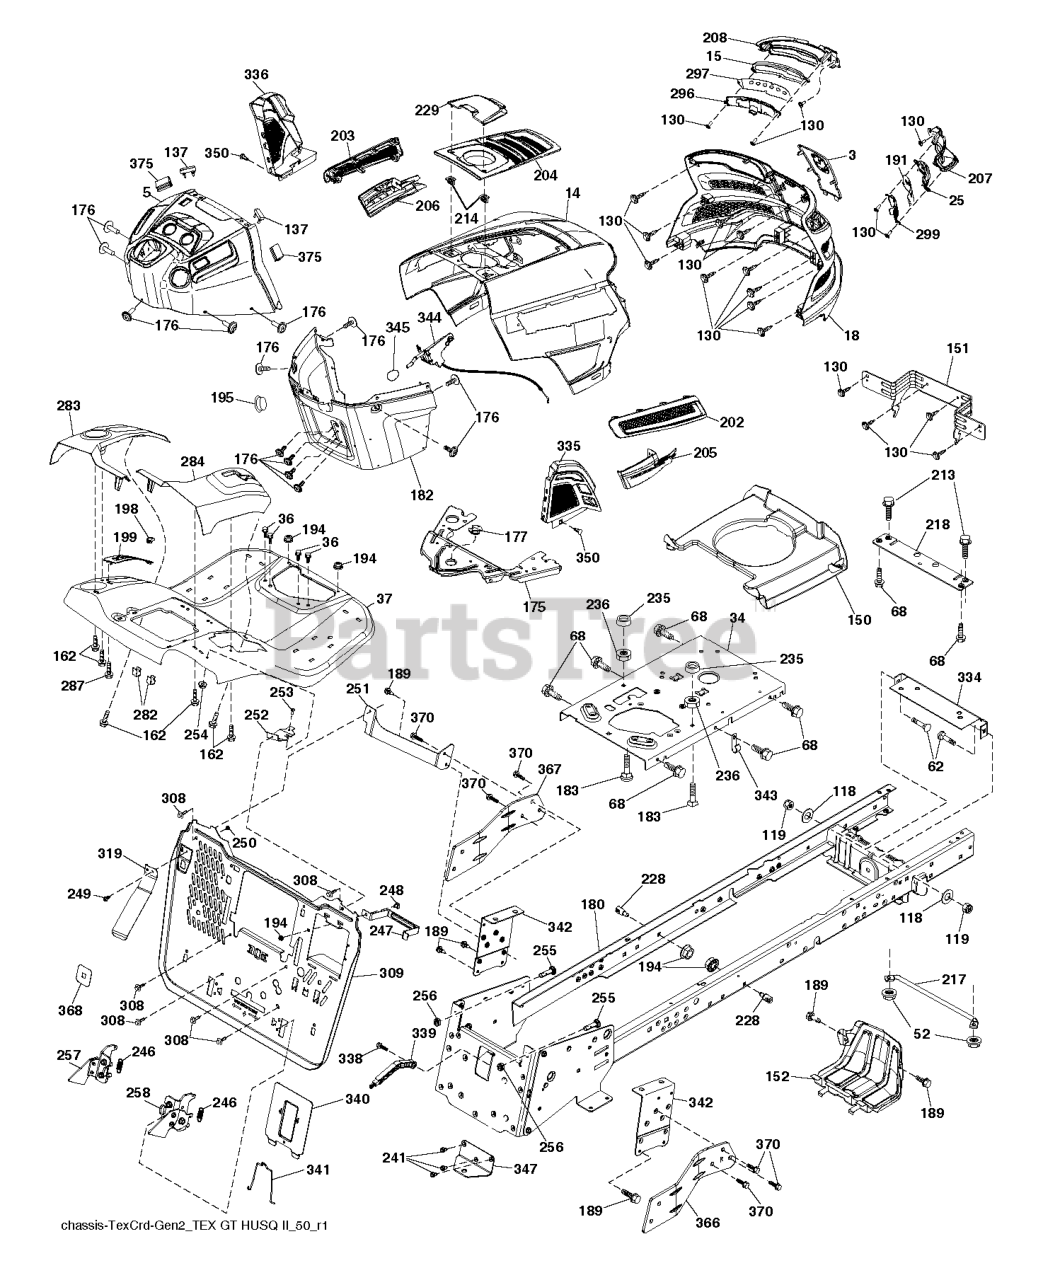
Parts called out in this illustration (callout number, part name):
3	APPLIQUE.SUBASM.GT.HUSQ.II
5	DASH.UPR.GT2.DUAL.RD.PT
14	HOOD.ASM.HUSQVARNA.GT.TEX.ORAN
15	LED LIGHT.LH
18	GRILLE SUBASM.GT.II.LOW.HDLGHT
25	LENS.RH
34	PLATE.ENGINE.10GA.CRD.GENII
36	SCREW 5/16"
37	FENDER.TEX.SRD.CRD.BASE
52	LOCKNUT
62	BOLT D
68	SCR 5/16-18 X 1/2 SELFTAP ZN
118	WASHER
130	SCREW.#10 X 0.750.BOS
137	BUMPER DASH
150	AIR DUCT.GTV2(1.66"RING HEIGHT
151	BRACKET.PIVOT.HOOD.GT.HUSQ.II
152	SHIELD.BROWNING.PNT.GT.V2
162	SCREW.HI-LO.CONSOLE
175	PLATE.PNT.CROSSMEMBER.HUSQ/PRE
176	SCREW.#10-24X5/8.RN.QU
177	BUSHING STEERING
180	Husqvarna TBD
182	DASH DASH LOWER
183	BOLT.5/16-18X1-1/4 FULL THD
189	SCREW
191	INSERT INFLECT.RH
194	NUT LOCK HEX FLANGE 5/16-18
195	PLUG.HOLE.DASH.LOWER.12V.BLK
198	INDICATOR.DECK.LIFT.RED
199	PLATE DECK LIFT
202	VENT.SIDE.RH.GT.HUSQ.II.
203	VENT.SIDE.LH.GT.HUSQ.II.498
204	VENT.TOP.EXTERNAL.FILL.GT2.GRE
205	SIDE.TRIM.RH.GT.HUSQ.II
206	SIDE.TRIM.LH.GT.HUSQ.II.GRAY
207	BEZEL GT2 LED RH W/ LOWER.ATT
208	BEZEL GT2 LED LH W/ LOWER ATT
213	HCS 5/16C X 3/4
214	CLIP.RETAINER.TINNER.
217	ROD.PIVOT.HOOD
218	X-PIECE.HOOD.STOP.NON/
228	STUD.FASTNER.W/ANTI-ROTATE
229	LID.EXT.FILL.GT.HUSQ2.BLACK
235	1/4-20X3/4 CARR BLT
236	NUT.CENTERLOCK.5/16-
241	SCREW 5/16-18X1
246	SPRING.LTCH.BGR.GEN2.5.CRD.TEX
247	STRAP.BATTERY.TCRD.GEN2.5X431
248	BOLT.CARR.5/16-18X1/2
249	SCREW.BUTTONHD.10-24X1/2.(2 2)
250	NUT 10-24 NYLOC
251	BRACKET.PNT.LH.SUPP.BKPLT.EDIP
252	BRACKET.PNT.RH.SUPP.BKPLT.EDIP
253	BOLT
254	NUT T
255	BOLT CROSS DRILLED CUP HEAD SQ
256	NUT.HEX.3/8-16
257	LATCH.ASM.BGR.LH.GEN2.5.STMPD
258	LATCH.ASM.BGR.RH.GEN2.5.STMPD
282	CLIP.RETAINER.CONSOLE.LT.HUSQ
283	CONSOLE.DECKLIFT.CRDII.498
284	CONSOLE.PEDAL.HYDRO
287	SCREW 1/4X20
296	LED LIGHT.LH
297	INSERT REFECT LH
299	LED LIGHT.RH
308	BOLT.5/16-18UNCX3/4 W/SEMS.BLK
309	BACKPLATE.TEXCRD2.5.BAGGER.479
319	LEVER.PRSNC.BGR.TEX.CRD.GEN2.1
334	BRACKET.ENGINE
335	COVER.LOWER.DASH.RH.BLACK
336	COVER-LH.LOWER.DASH.GT2.BLACK
338	BOLT BOLT SHOULDER
339	LEVER LEVER BAGGER
340	BATTERY.DOOR.TCRD.GEN2.5.MS479
341	LATCH.BATTERY.DOOR.TCRD
342	SUPPORT.PNT.FENDER.CRD.TEX
343	CLIP CLIP
344	CONTROL.EZ.MULCH.TEX/CRD
345	RP KNOB.OVAL.TAPERED.3/8-16BLK
347	HITCH HITCH TOW TEX CRD GEN 2
350	CLIP.X-MAS.TREE
366	BRACKET.RH.FRONT.BAGGER.BLACK
367	BRACKET.LH.FRONT.BAGGER.BLACK
368	FULL.LEVER.BAGGER.TEX.CRD
370	SCREW 3/8-16X1
375	BUMPER CLIP-ON. DASH 1"
